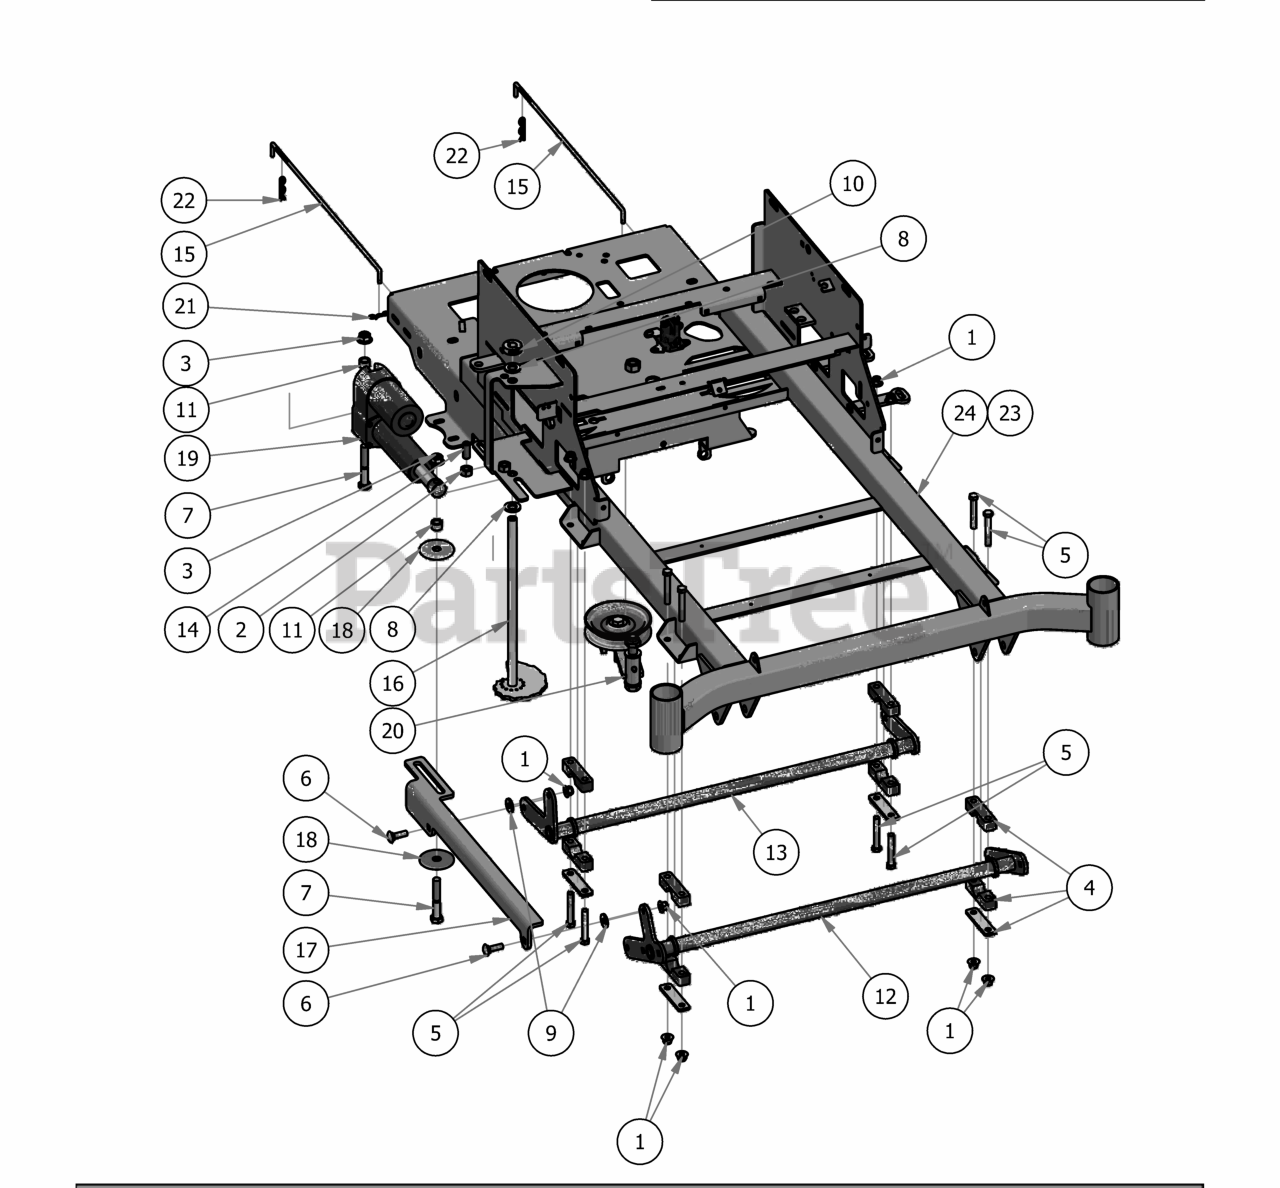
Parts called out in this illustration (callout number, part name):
1	3/8 Nylock Flange Nut
2	1/2" Hex Nut
3	1/2-13 Nylon Insert Flange Nut Zinc Orange Nylon
4	Pillow Block Kit
5	3/8-16 x 2 1/2" Hex Bolt
6	3/8" x 1 1/4" Carriage Bolt
7	1/2 x 2-3/4 Hex Bolt
8	.630 ID x 1.122 OD x .142 THK Plastic Washer
9	.360 ID Plastic Washer
10	5/8" Split Collar
11	1/2 x 1/2 Spacer
12	Actuator Bar Front- 2017 MZ/ZT
13	Actuator Bar Rear- 2017 MZ/ZT
14	Dial Rod Plunger
15	Neutral Rod
16	ZT Deck Height Bar Assembly
17	2017 MZ/ZT Actuator Linkage
18	Snubbing Washer
20	ZT Pump Idler
22	Neutral Rod Clip
23	ZT 54" and 60" Frame
24	2017 MZ/ZT 42"-48" Frame
